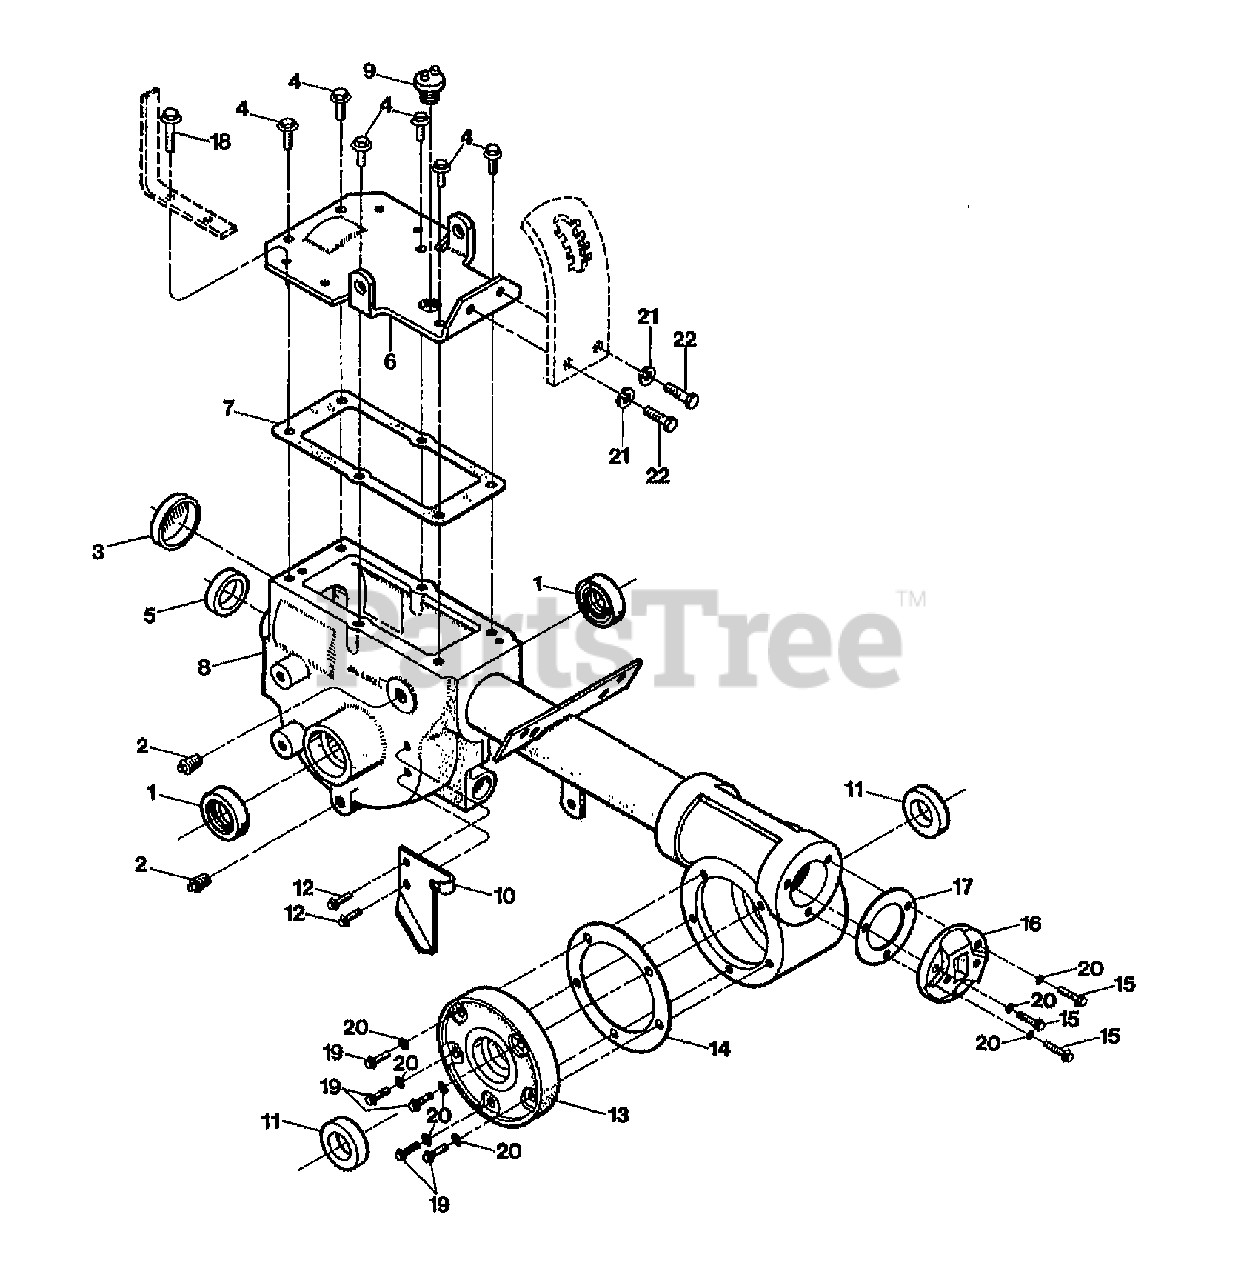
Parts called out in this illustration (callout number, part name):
1	SEAL-OIL WHEELSHAFT
2	PLUG-PIPE 1/4 NPT
3	SEAL-BORE
4	SCR-HFLK 5/16-18X.75 ZP
5	SEAL-PINION SHAFT PT/85030/00
6	KIT-COVER TRANS W/HDW (INCL. FOUR OF 18, TWO EACH OF 21, 22)
7	GASKET-TRANS COVER
8	ASSM-TRANS A-UNIT P/ECHO
9	PLUG-OIL FILL 3/4-10
10	PLATE-CABLE MT PNT
11	SEAL-TILLER SHAFT
12	SCR-HFLK 5/16-18X.62 G5ZP
13	COVER-TILLER HSG MACH (INCL. FIVE SCREWS,#19)
14	GASKET-TILLER COVER (FITS ALL COVERS)
15	SCR-HFLK 1/4-20X.875
16	CAP-REAR #1115
17	GASKET-BRG COVER
18	SCR-HFLK 5/16-18X1.00 ZP
19	SCR-HH 1/4-20X.625
20	WASHERS, NYLON. NOT REUSEABLE
21	WASHER-LK .375 @ DEPL
22	SCR-HH 3/8-16X.75 G5 ZP
